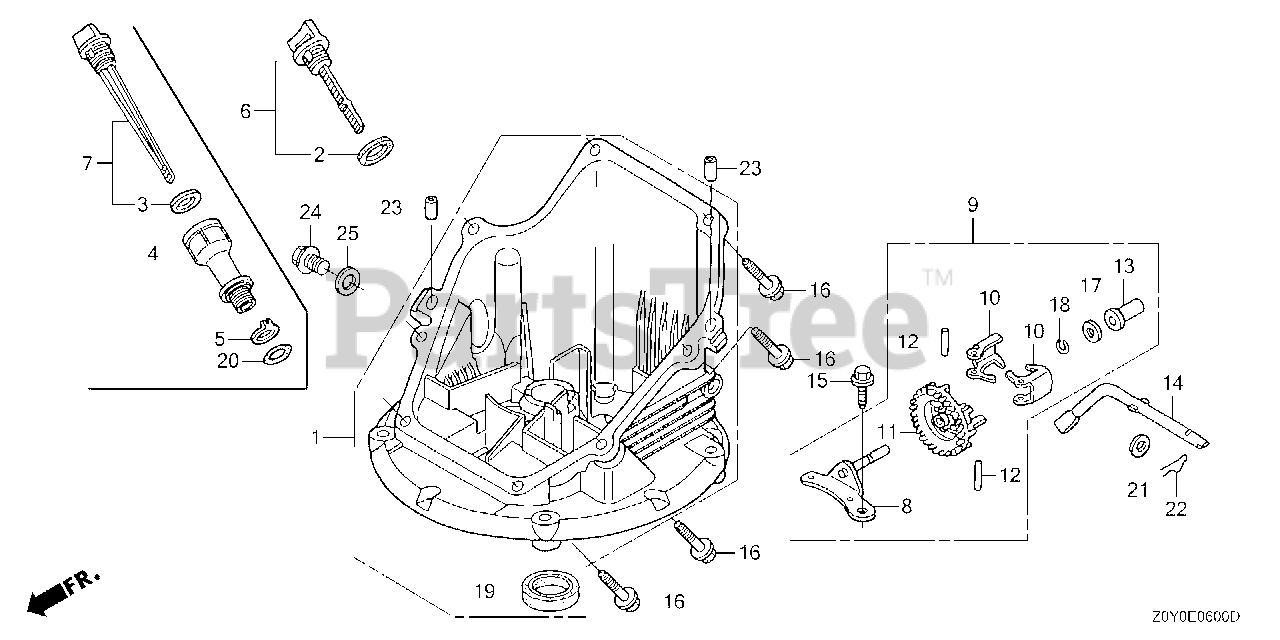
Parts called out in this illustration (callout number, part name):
1	PAN ASSY., OIL
3	GASKET, OIL FILLER CAP
4	EXTENSION, OIL FILLER
5	WASHER, EXTENSION LOCK
7	GAUGE ASSY., OIL LEVEL
8	SHAFT, GOVERNOR HOLDER
9	GOVERNOR ASSY.
10	WEIGHT, GOVERNOR
11	HOLDER, GOVERNOR WEIGHT
12	PIN, GOVERNOR WEIGHT
13	SLIDER, GOVERNOR
14	SHAFT, GOVERNOR ARM
15	BOLT, FLANGE (6X14) (CT200)
16	BOLT, FLANGE (6X25) (CT200)
17	WASHER, THRUST (6MM)
18	CLIP, GOVERNOR HOLDER
19	OIL SEAL (28X41.25X6)
20	O-RING (14.8X2.4) (ARAI)
21	WASHER, PLAIN (6MM)
22	PIN, LOCK (8MM)
23	PIN, DOWEL (8X20)
